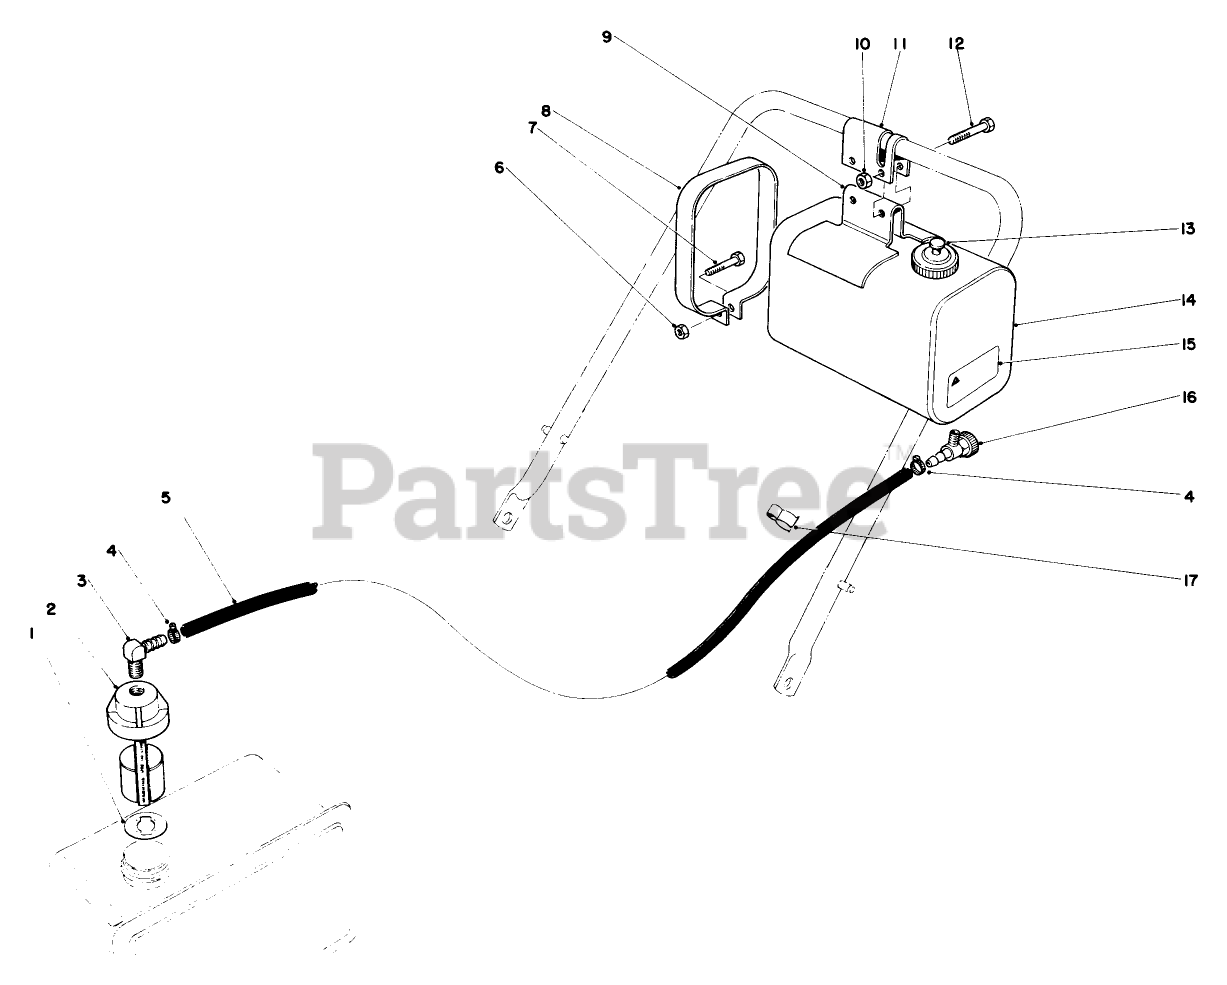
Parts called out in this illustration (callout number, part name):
2	FUEL CONT VALVE ASM
3	CONNECTOR-HOSE
4	CLAMP-HOSE
7	SCREW-HH
12	SCREW-HH
